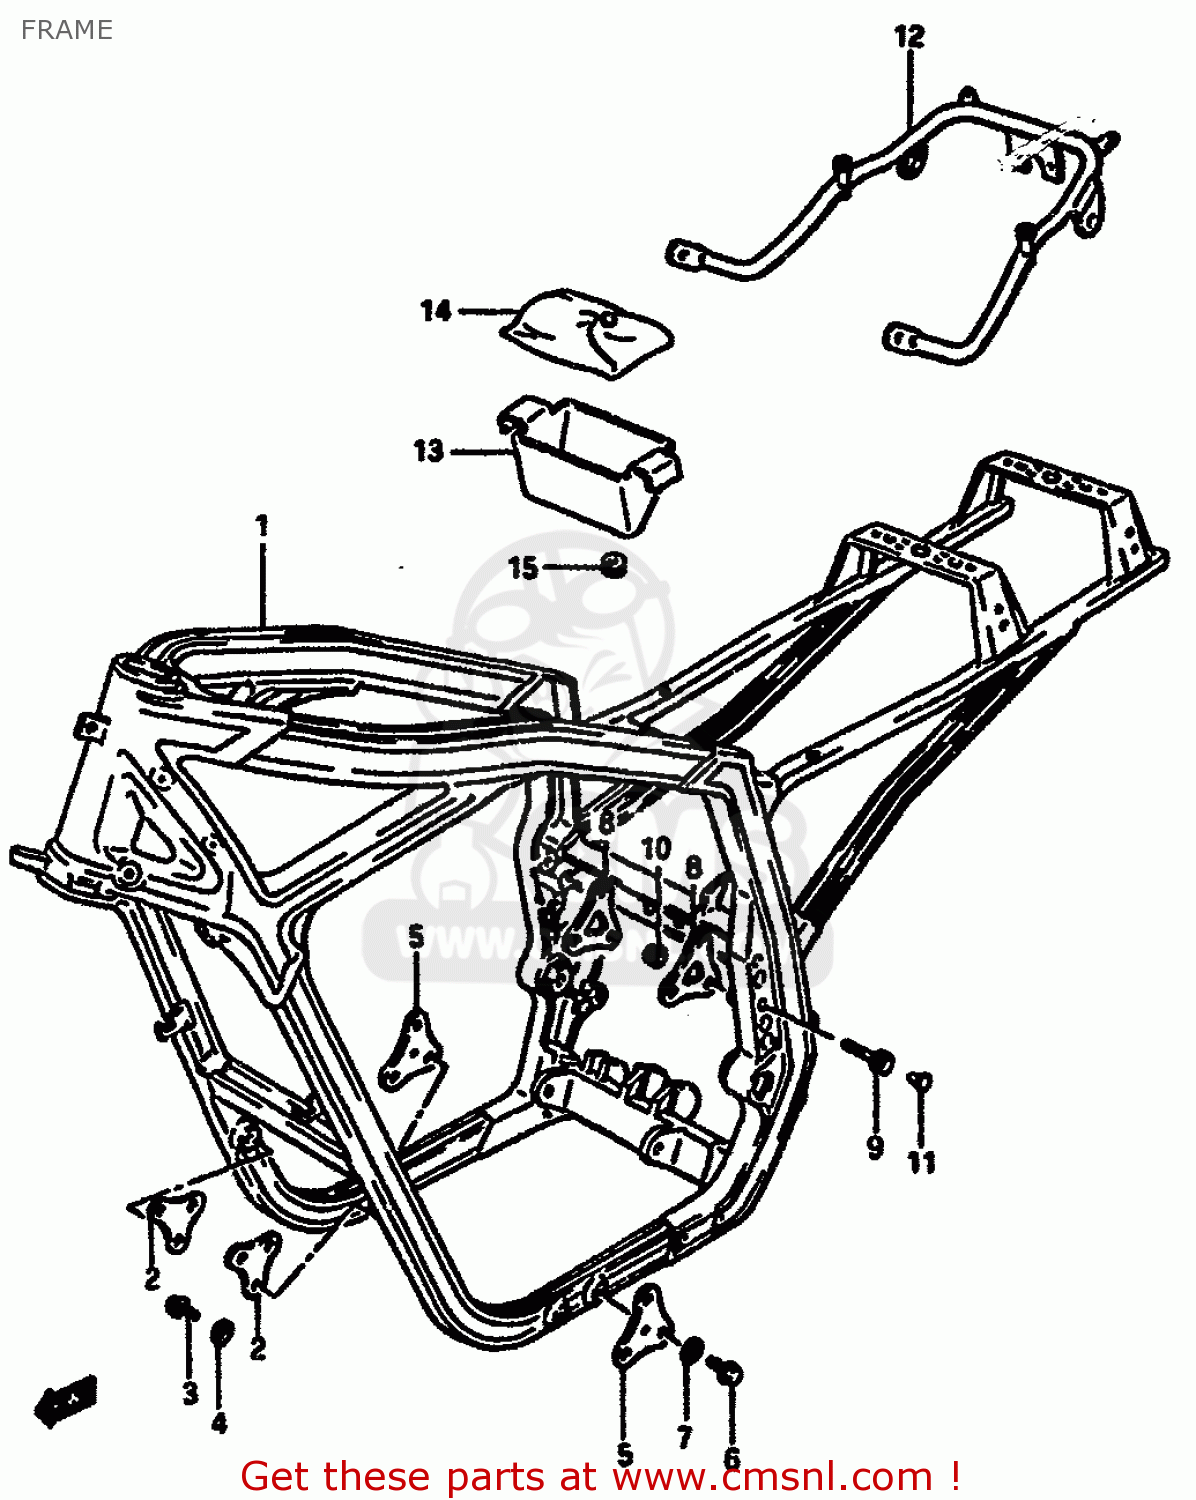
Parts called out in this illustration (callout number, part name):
1	FRAME
2	PLATE,ENGINE MOUNTING NO
3	BOLT
4	WASHER (8.2X20X1.6)
5	PLATE,ENGINE MOUNTING NO.1
6	BOLT
7	WASHER (8.2X20X1.6)
8	PLATE,ENGINE MOUNTING NO
9	BOLT, RH
10	NUT
11	CAP,ENGINE MOUNTING
12	GRIP,REAR
13	HOLDER,TOOL
14	TOOL ASSY
15	CUSHION
